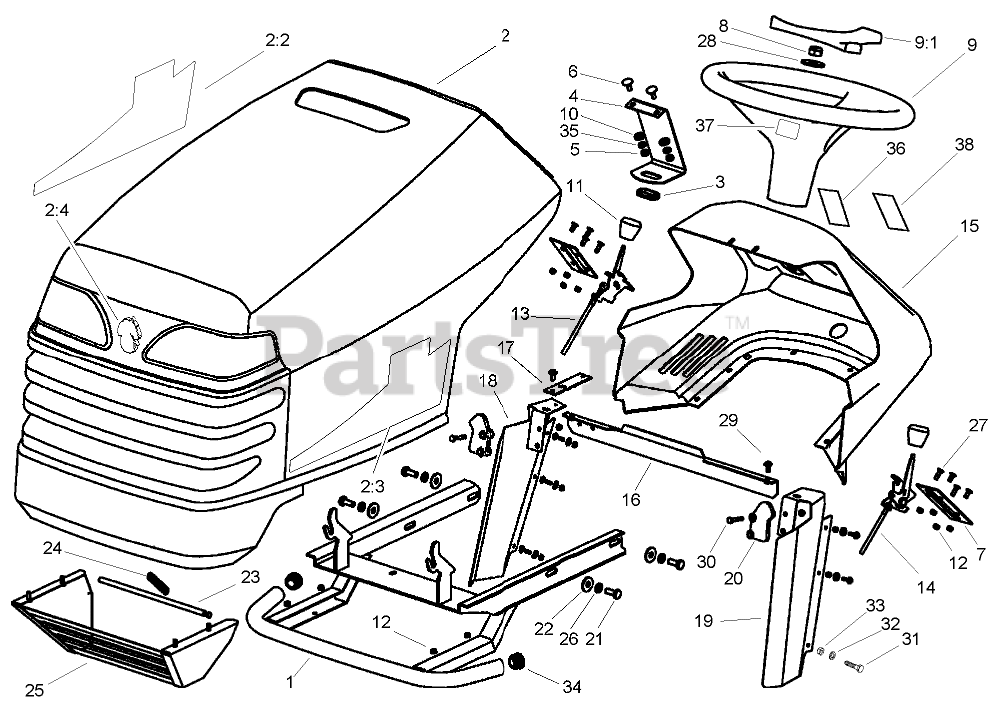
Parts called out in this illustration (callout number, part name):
1	SUPPORT-BUMPER
2:2	DECAL-HOOD, RH
2:3	DECAL-HOOD, LH
2:4	EMBLEM
3	BUSHING
4	HOLDER-TANK, FUEL
5	NUT-LOCK
8	NUT-LOCK
9	WHEEL-STEERING
9:1	COVER-WHEEL, STEERING
10	WASHER-PLAIN
12	NUT-LOCK
13	CONTROL-THROTTLE (TWIN)
14	CONTROL-CHOKE (TWIN)
15	PANEL-DASH
17	BRACKET
18	PANEL-RIGHT
19	PANEL-LEFT
20	LATCH-HOOD
21	SCREW-HH
22	WASHER-PLAIN
23	BAR-SAFETY
24	SPRING-HOOD
25	GUARD-MUFFLER
26	WASHER-LOCK, SPRING
28	Washer
32	WASHER
33	NUT-HEX
34	PLUG-END, TUBE
35	WASHER-LOCK, SPRING
36	DECAL
37	DECAL
38	DECAL-CHOKE/PTO
